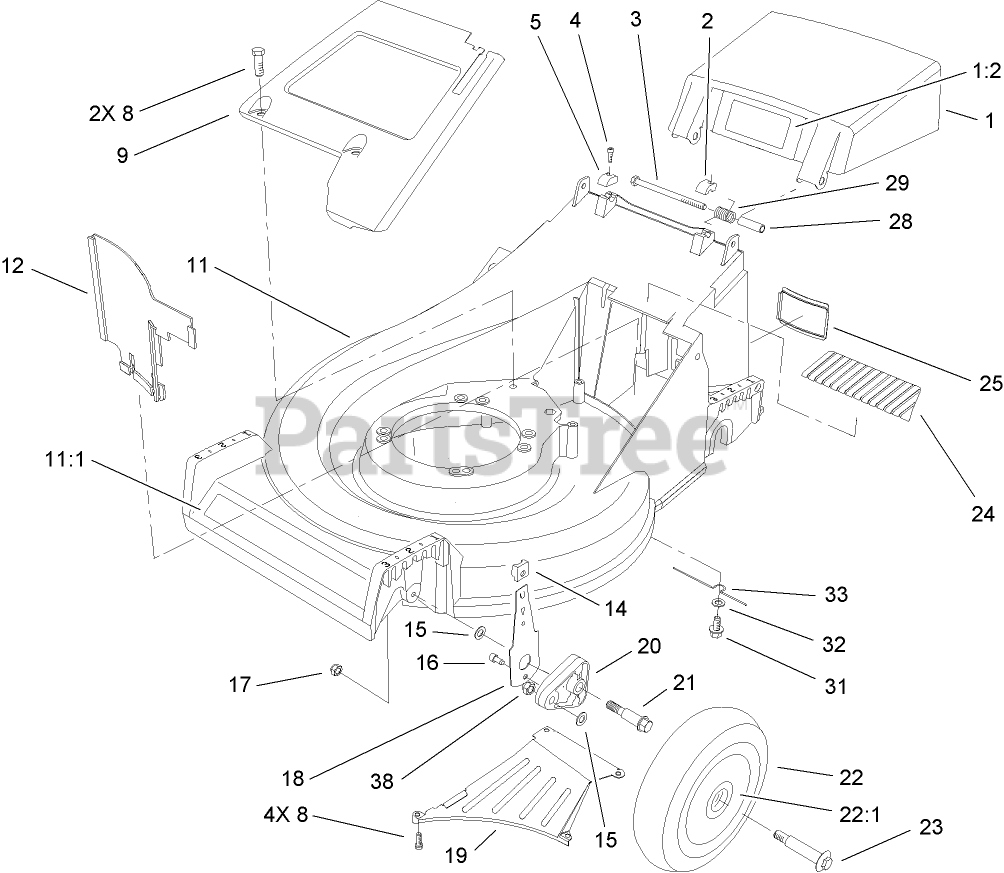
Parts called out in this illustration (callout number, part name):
1	DOOR-BAG
1:2	DECAL-WARNING
2	CAP-HINGE BOLT, LH
3	SCREW-HH
4	SCREW-HSH
5	CAP-HINGE BOLT, RH
8	SCREW-HWHTF
9	PANEL-SCREEN
11	HOUSING ASM
11:1	DECAL
12	PANEL-VERTICAL
14	KNOB-ARM
15	WASHER
16	SCREW-HWH
17	NUT-LOCK
18	FRONT SPRING ARM ASM
20	ARM-PIVOT, FRONT
21	BOLT-SHOULDER
22	WHEEL ASM
22:1	BUSHING
23	BOLT-SHOULDER
24	COVER-TOP
25	COVER-ACCESS
28	SPACER-DOOR
29	SPRING-DOOR
31	SCREW-HHFTF
32	WASHER-FLAT
33	RETAINER-BELT
38	LOCKNUT
